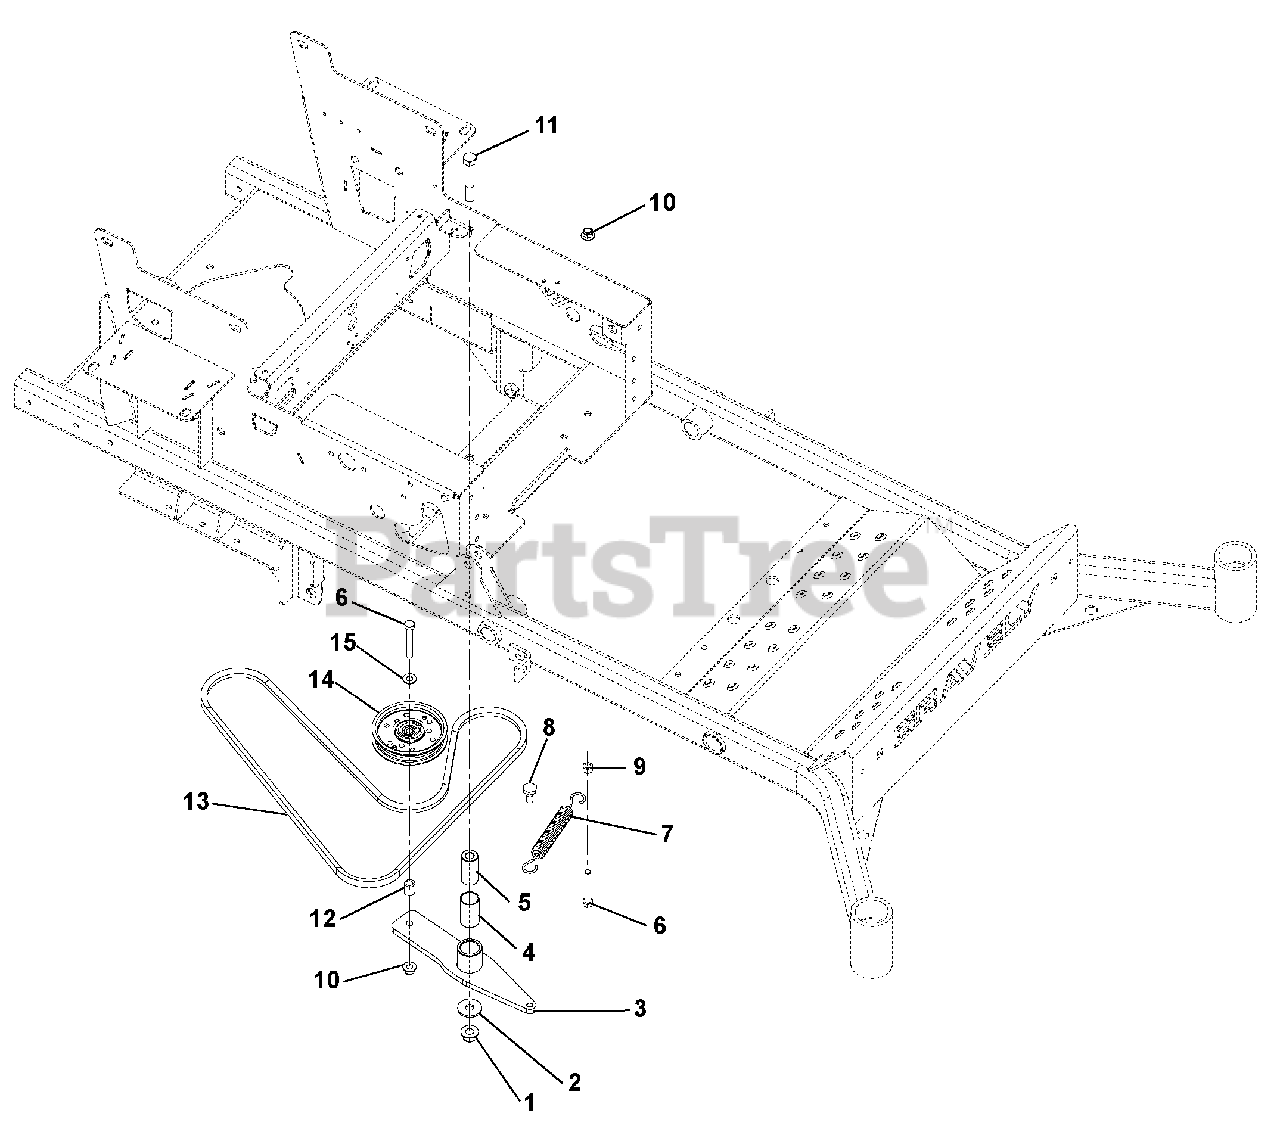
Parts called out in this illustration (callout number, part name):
1	NUT-LK-NYL-FLG .50-13 YWZC
2	WSHR-FL-STL.511X1.441X.125 YWZ
3	WMT, HYDRO DRIVE IDLER ARM
4	BSHG, 1.00 X 1.125 X 1.937
5	BSHG, SPCR .502X.997X2.03 PM
6	BLT-HEX .38-16X2.50 GR5 YWZC
7	SPRING, EXTENSION
8	BLT,SHLDR EP .38-16X.30 HEX YZ
9	NUT-HEX .38-16 YWZC
10	NUT-LK-NYL-FLG .38-16 YWZC
11	BLT-HEX .50-13X3.25 GR5 YWZC
12	BSHG-SLV .407X.625X.750 PL
13	V-BELT, A-COGGED
14	IDLER-FLAT 4.00 X .38 NWHAMSHR
15	WSHR-FL-STL.406X.812X.065 YWZ
